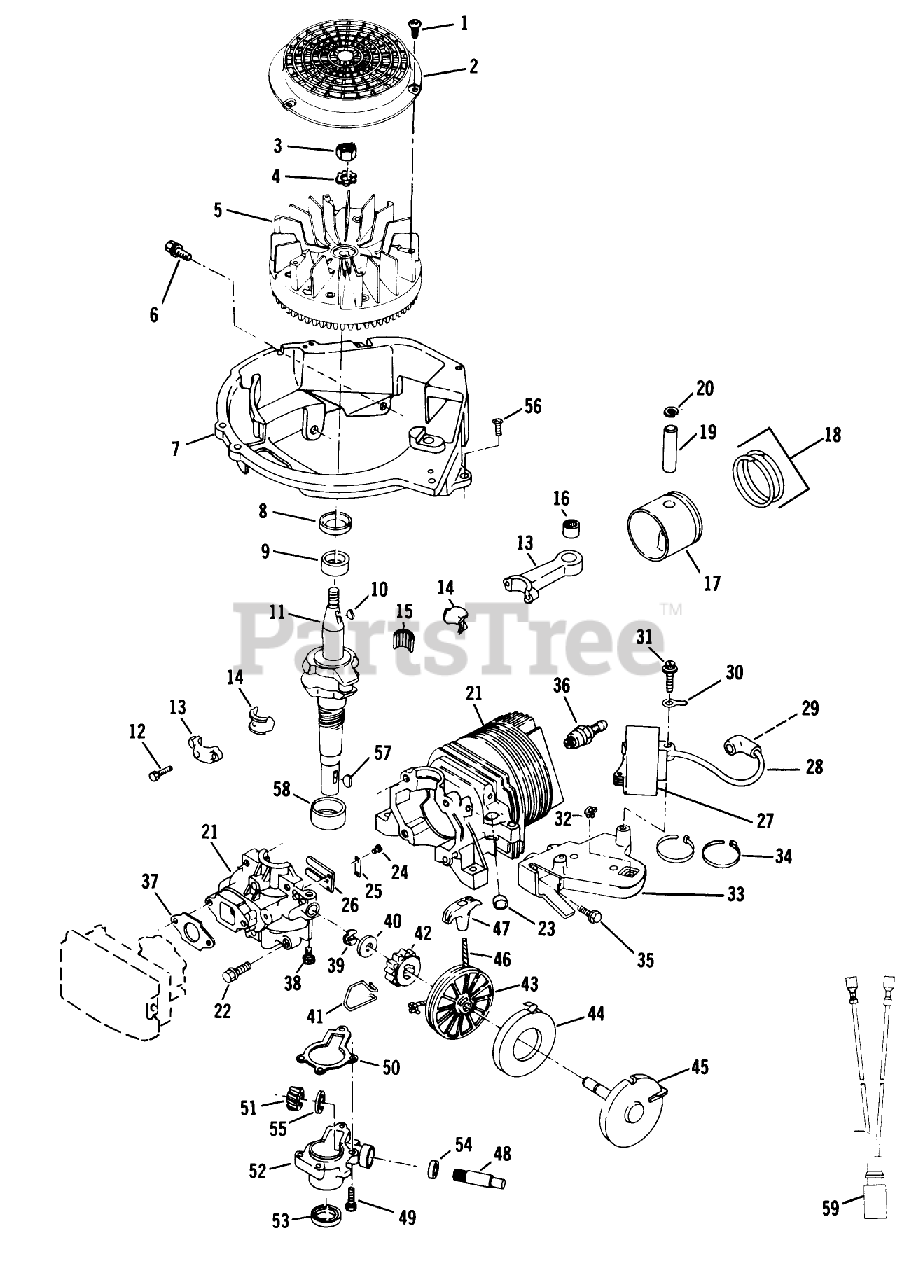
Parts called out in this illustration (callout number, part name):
1	SCREW F
2	SCREEN F'WHEEL S
6	SCREW-SEMS
9	BEARING V
12	SCREW-HSH
14	LINER ASM
16	BEARING AY F
20	RING-RETAINING
22	SCREW S
23	PLUG-CORE VF
25	PLATE-BACKUP, REED
28	HT LEAD&COVER XEV
30	TERMINAL S
32	NUT-CLIP
33	BRACKET S
37	GASKET CARB S
40	WASHER S
41	SPRING F
43	PULLEY STARTER S
47	HANDLE STARTER S
50	GASKET S
51	GEAR, DR SHAFT S
53	SEAL-OIL
55	THRUST WASHER
56	SCREW F
58	BEARING S
59	WIRE HARNESS
